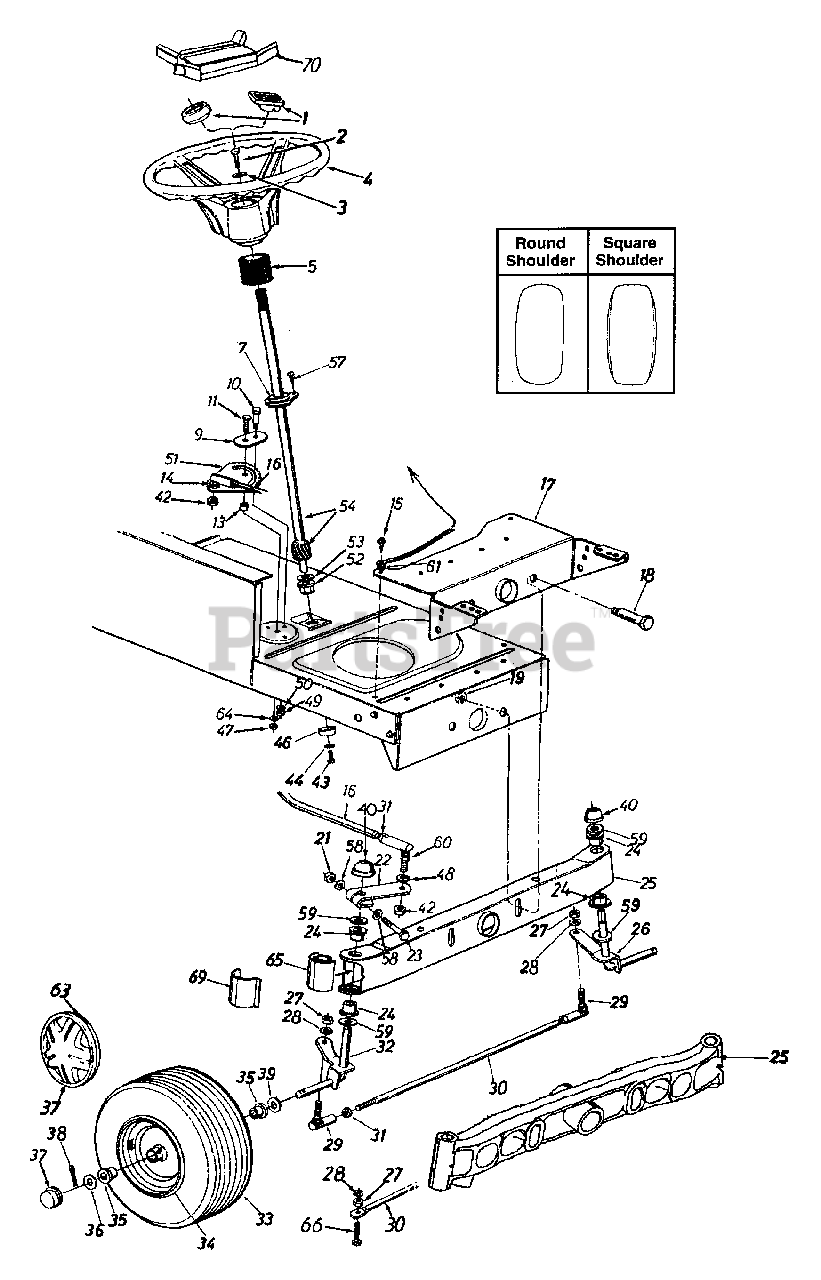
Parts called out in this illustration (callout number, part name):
1	Steering Wheel Cap
2	Hex Bolt 5/16-18 x 1" Lg.
3	Belleville Wash. .345" I.D.
4	Steering Wheel (3 Spoke)
5	Steering Bellow-4.5" (Style A)
7	Flange Bearing.628" I.D. x 1.36 O.D.
9	Retainer Plate
10	Shoulder Bolt.437 x .35 Lg. 5/16-18
11	Hex Bolt 3/8-24 x 1.0" Lg. (Gr. 5)
13	Spacer.380" I.D. x .625" O.D.x
14	Lock Washer 3/8" I.D. (H.D.)
15	Hex Wash. Hd. Self-Tap Scr.
16	Steering Drag Link
18	Shoulder Bolt
21	Hex Lock Nut 5/16-24 Thd.
22	Steering Arm Front Axle
23	Hex Bolt 5/16-24 x 2.25" Lg.
24	Hex Flg. Brg. .632 I.D.
26	Front Axle Assembly-LH 15" x 6" (Round & Square Shoulder)
26	Front Axle Assembly-LH (46" Deck) 15" x 6" (Round & Square Shoulder)
27	Hex Nut 3/8-24 Thd.
28	Lock Washer 3/8" I.D.
29	Ball Joint 3/8-24 Thd.
30	Tie Rod (Adjustable)
31	Hex Jam Nut 3/8-24 Thd.
32	Front Axle Assembly-RH 15" x 6" (Round & Square Shoulder)
32	Front Axle Assembly-RH (46" Deck) 15" x 6" (Round & Square Shoulder)
35	Bearing 15" x 6" (Round Shoulder)
37	Front Wheel Hub Cap
38	Cotter Pin 1/8" Dia. x 1.25"
39	Flat Washer .640" I.D. x 1.20" O.D.
40	Push Cap 5/8" Dia. Rod
42	Hex Jam Nut 3/8-24 Thd.
43	Hex Patch Bolt 5/16-18 x .62"
46	Cap
47	Hex Cent. Lock Nut 3/8-24 Thd.
48	Lock Washer 3/8" I.D.
49	Hex Cent. Lock Nut 5/16-18 Thd.
50	Lock Washer 5/16" I.D.
51	Steering Gear Segment
52	Hex Fig. Brg. .634 I.D.
53	Flat Washer (Hardened)
54	Steering Shaft
57	Oval Hd. C.Sunk Scr. (Style A)
58	Wave-Wash 32" I.D. x .62" O.D.
59	Flat Washer (Hardened)
60	Drag Link Ball Joint 7/16-20 Thd.
63	Spring Clip (Used w/Spoked Hub Cap)
64	Washer .39" I.D. x 1.38" O.D.
65	Pivot Bar End Cap (If equipped)
66	Hex Bolt 3/8-24 x 1.5" Lg. (Gr. 5)
69	Axle Cap
70	Steering Wheel Insert (it equipped)
